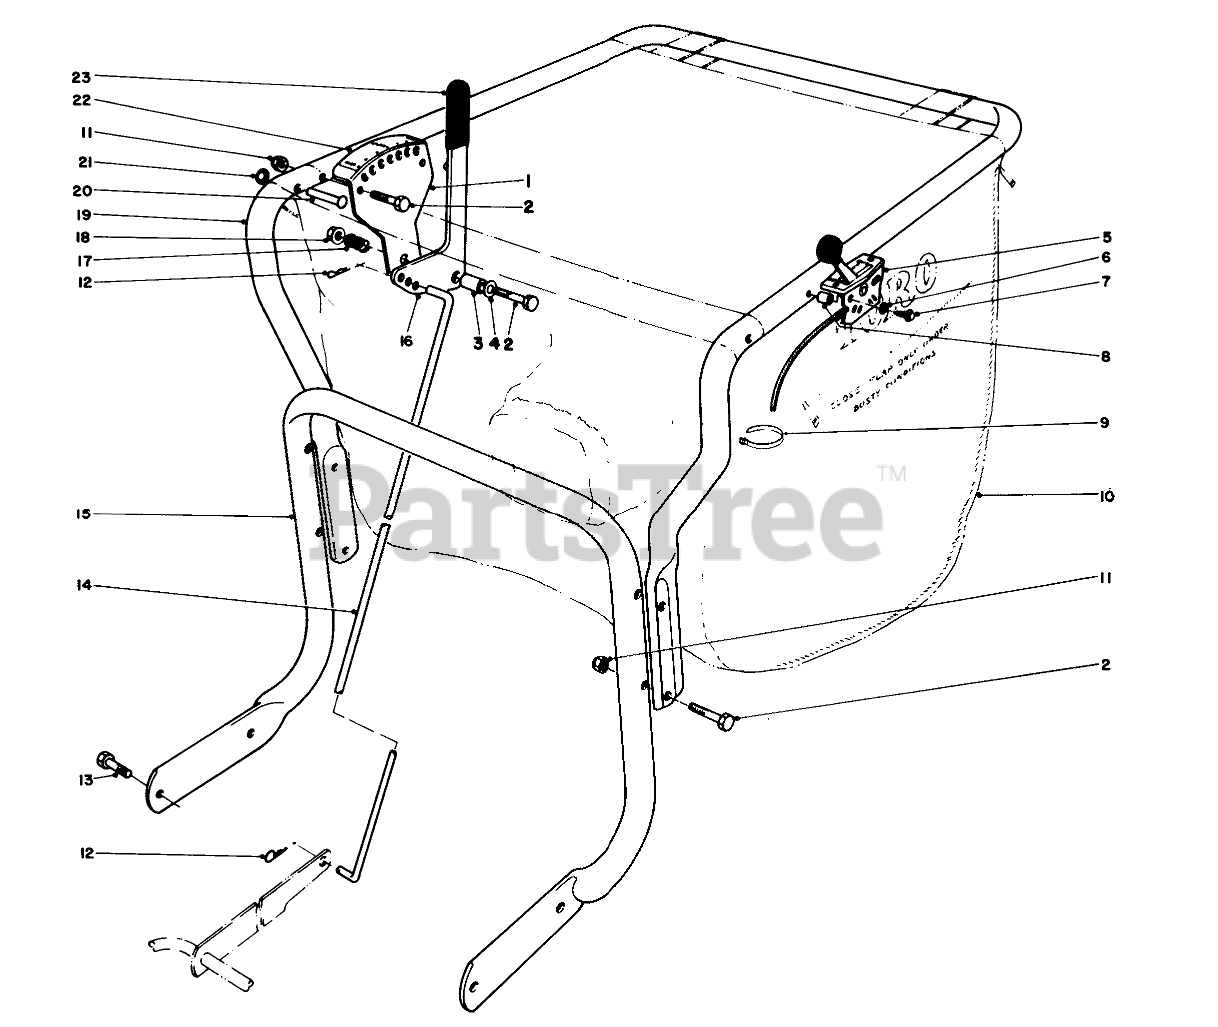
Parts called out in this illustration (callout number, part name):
1	Adjustment Bracket
2	SCREW-HH
3	SPACER
4	WASHER-FLAT
5	THROTTLE CONTROL
6	WASHER-LOCK, EXT
7	10-24 X 1 PAN HD SCR
8	SPACER
9	TIE-CABLE
10	Bag-Vacuum
11	NUT-LOCK, CONE
12	PIN-COTTER
13	SCREW-HH
14	HEIGHT ADJ. ROD
15	HANDLE
16	Handle-Adjustment
17	SPRING-COMPRESSION
18	NUT-HF
19	HANDLE-UPPER, VACUUM
20	RIVET
21	Push Nut
22	HT ADJ DECAL
23	GRIP-HANDLE
